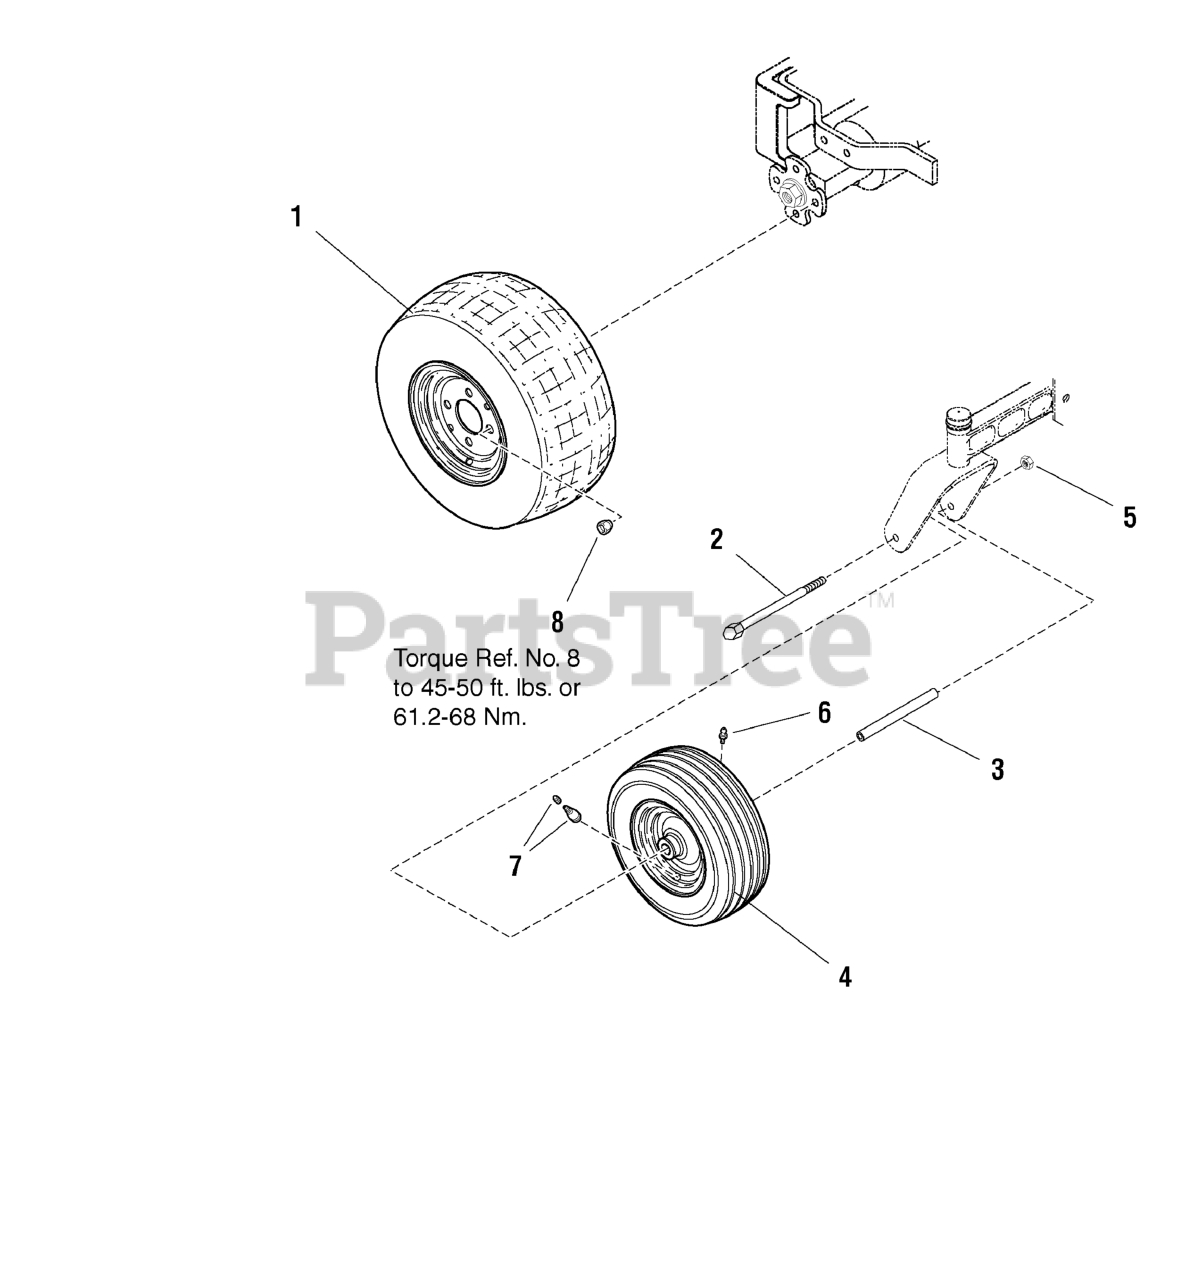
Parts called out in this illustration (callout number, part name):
1	WHEEL & TIRE ASSEMBLY, 18 x 8-1/2-8
2	CAPSCREW, Hex Head
3	TUBE, Caster Wheel Spacer
4	WHEEL & TIRE ASSEMBLY, 11 x 4-5
5	NUT, Hex Center Lock
6	FITTING, Lube
7	VALVE STEM & CAP
8	NUT, Hex Lug, 7/16-20
